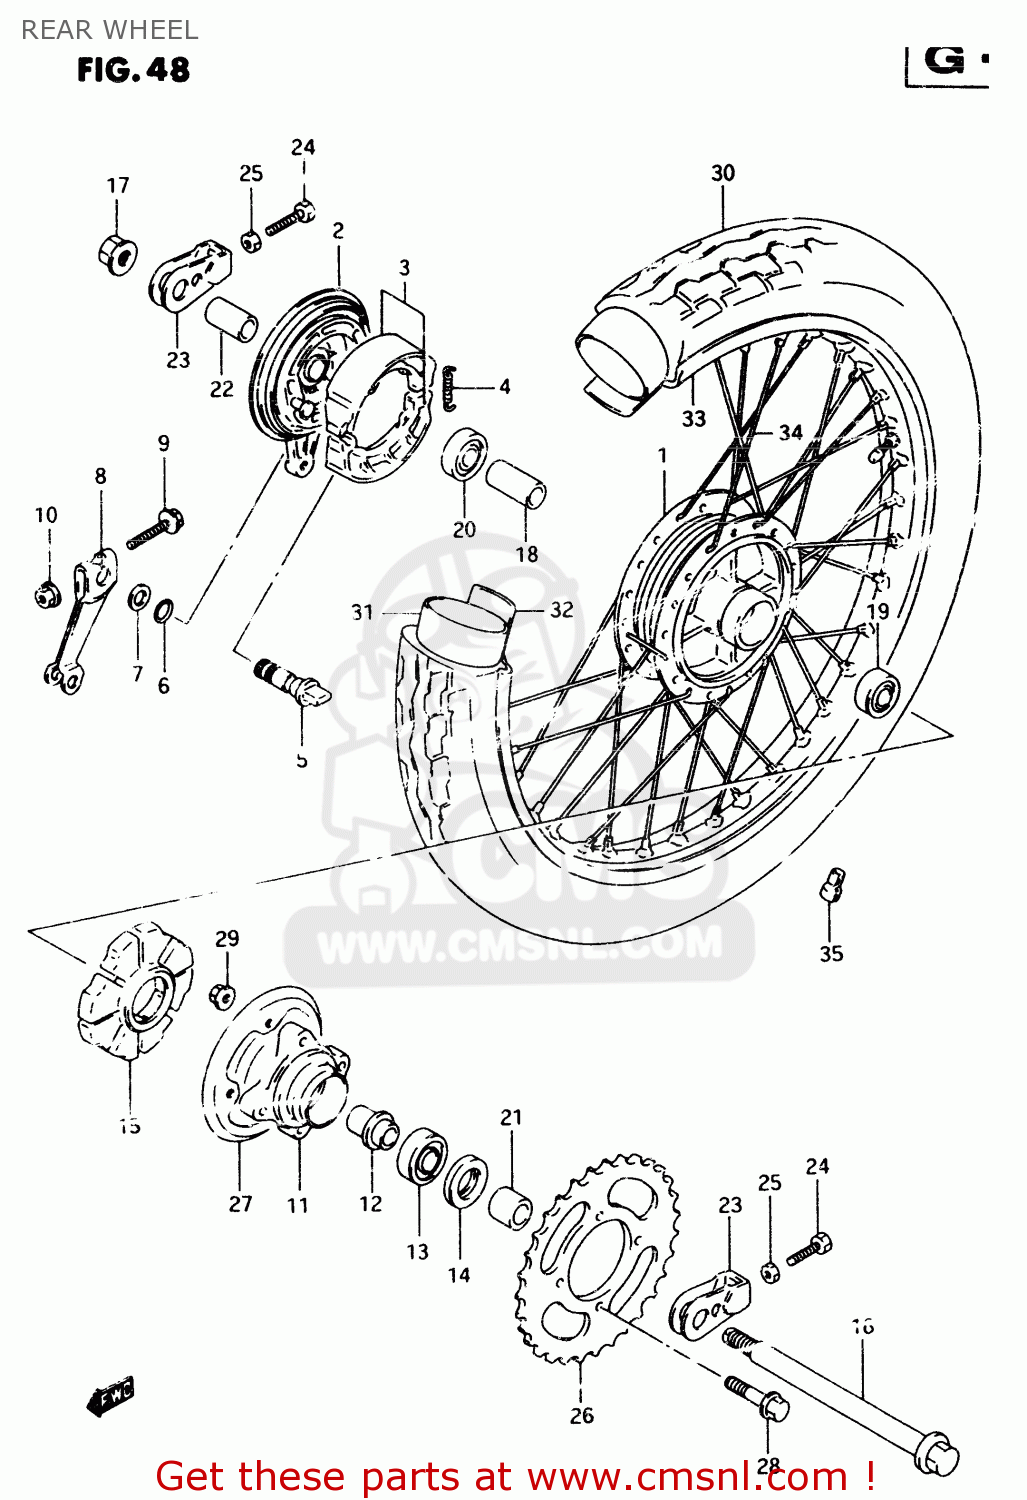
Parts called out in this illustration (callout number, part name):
1	HUB,RR WHEEL
2	PANEL,RR BRAKE ANCHOR
3	SHOE SET,BRAKE (NAS)
4	SPRING(L:34)
5	CAM,BRAKE
6	O RING(D:2.5,ID:13.8)
7	WASHER(14.5X22X1.6)
8	LEVER,RR BRAKE CAM
9	BOLT
10	NUT
11	DRUM,RR SPROCKET MOUNTING
12	RETAINER,RR SPROCKET DRUM
13	BEARING(20X47X14)
14	SEAL,OIL(28X47X7)
15	ABSORBER ASSY,HUB SHOCK
16	AXLE, REAR
17	NUT
18	SPACER(15.3X21.7X63)
19	BEARING
20	BEARING
21	SPACER(15X28X24.8)
22	SPACER(15X22X46.8)
23	ADJUSTER,CHAIN
24	BOLT(8X50)
25	NUT
26	SPROCKET,RR(NT:41-520)
27	GUIDE,RR SPROCKET CHAIN
28	BOLT(10X40)
29	NUT
30	TIRE,RR(120/80-17)
31	TUBE ASSY,WHEEL INNER
32	PROTECTOR,WHL INR TUBE
33	RIM, REAR WHEEL (2.50X17)
34	SPOKE ASSY,RR WHEEL
35	BALANCER,WHEEL (B)
